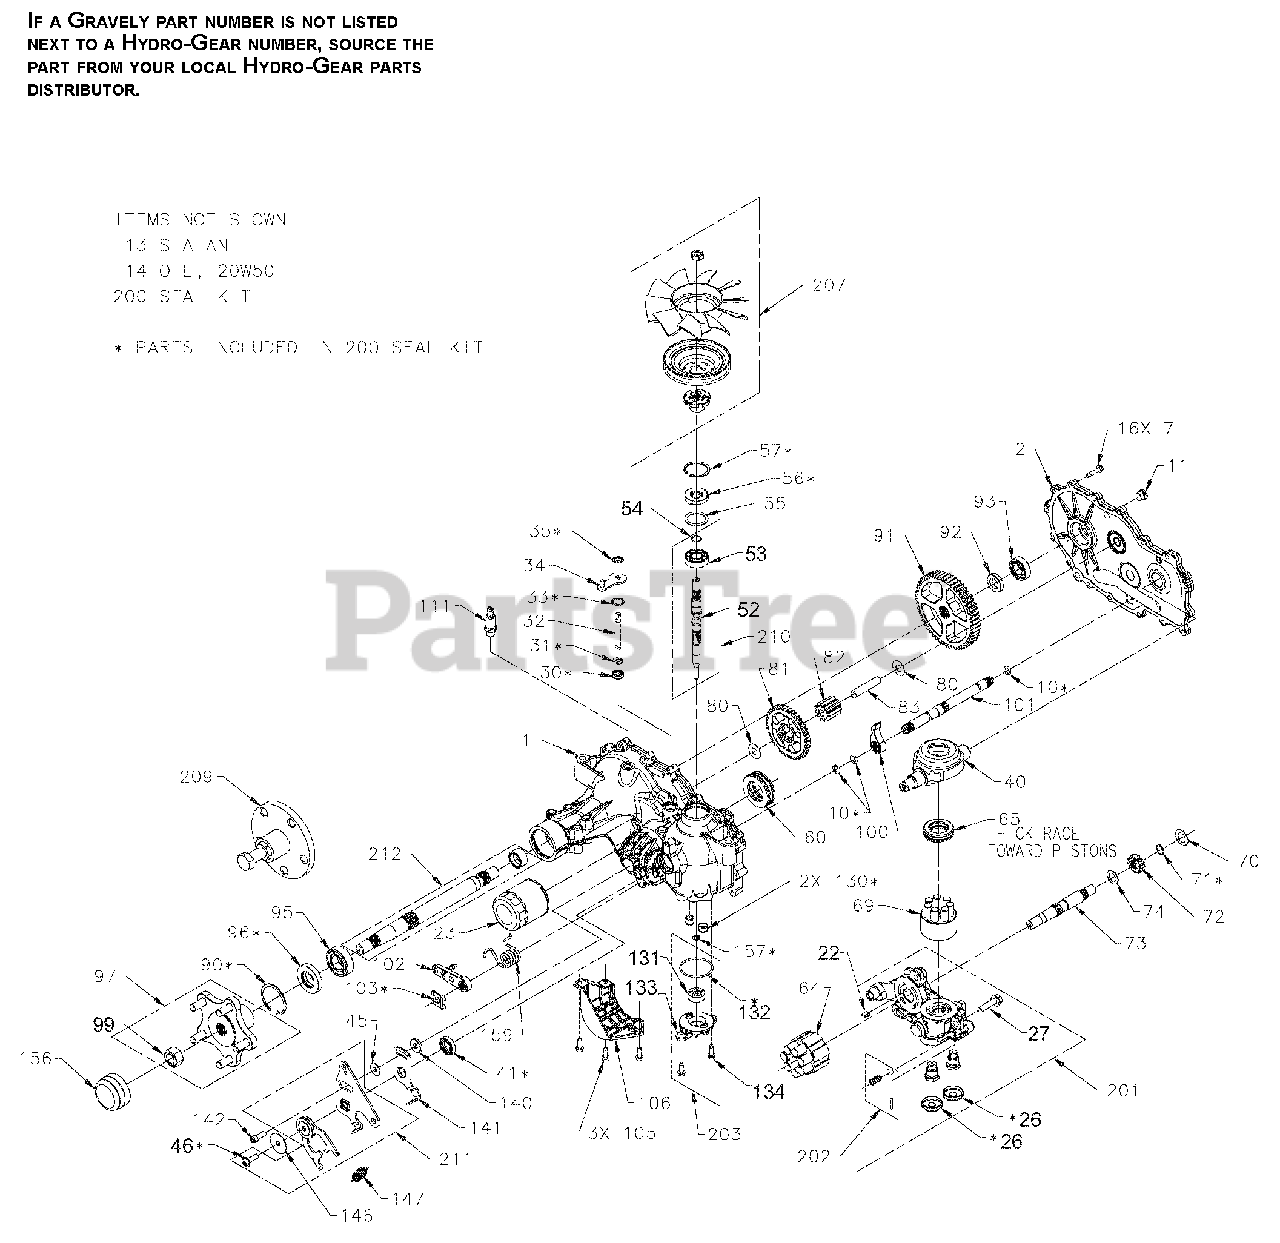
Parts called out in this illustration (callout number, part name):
7	HFHCS 1/4-20 x 1.25
11	Plug, 9/16-18 (Metal)
22	Plate, Bypass
23	Filter, Oil
26	Seal, Plug 1.25 x .25
30	Seal, Lip .375 x .75 x .25
31	Ring, Retention .375 External
33	Ring, Retention .750 Internal
34	Arm, Bypass
35	Ring, Retention .375 External
40	Trunnion, Swashplate
41	Seal, Lip 18 x 32 x 7
42	Stud, Short 5/16-24
45	Washer, .34 x .88 x .06
46	TWHCS 5/16-24 x 1.00
53	Bearing, Ball 17 x 40 x 12 Open 6203
54	Ring, Ret Wire .561 ID
55	Washer, 1.23 x 1.56 x .04
56	Seal, Lip 17 x 40 x 7
57	Ring, Ret 1.59 Internal
60	Bearing, Thrust
64	Assembly, Cylinder Block, 16cc
65	Bearing, Thrust Ball 30 x 52 x 13
69	Assembly, Block, 7 Piston
70	Washer, .63 x 1.0 x .05
71	Ring, Retaining .625
74	Washer, .72 x 1.16 x .04
80	Washer, .5 x 1.0 x .03
83	Jack Shaft
90	Ring, Ret 2.06 Internal
95	Bearing, Ball 1.0 x 52 x 15 Open 6205M
96	Seal, Lip TC4 1.0 x 2.06 x .38
99	Nut, Hex Lock 3/4-16
103	Clip, Retaining
105	HFHCS 1/4-20 x .75
111	Fitting, Str 9/16-18 SAE .5 Barb
131	Assembly, Gerotor Tang x 1.15 x .39
132	O-Ring, -137, 0.103 x 2.05
134	HFHCS 1/4-20 x .75
140	Spacer, .320 x 1.00 x .179
142	SHCS 5/16-24 x 1 Patch
146	Washer, .343 x 1.5 x .062
147	Spring, Extension Rtn - 34 lbs
200	Kit, Seal ( * - parts included in this kit)
210	Kit, Input Shaft (includes items 52, 53 and 54)
211	Kit, Rtn CCW (includes items 44, 46 and 145)
NS	Sealant
